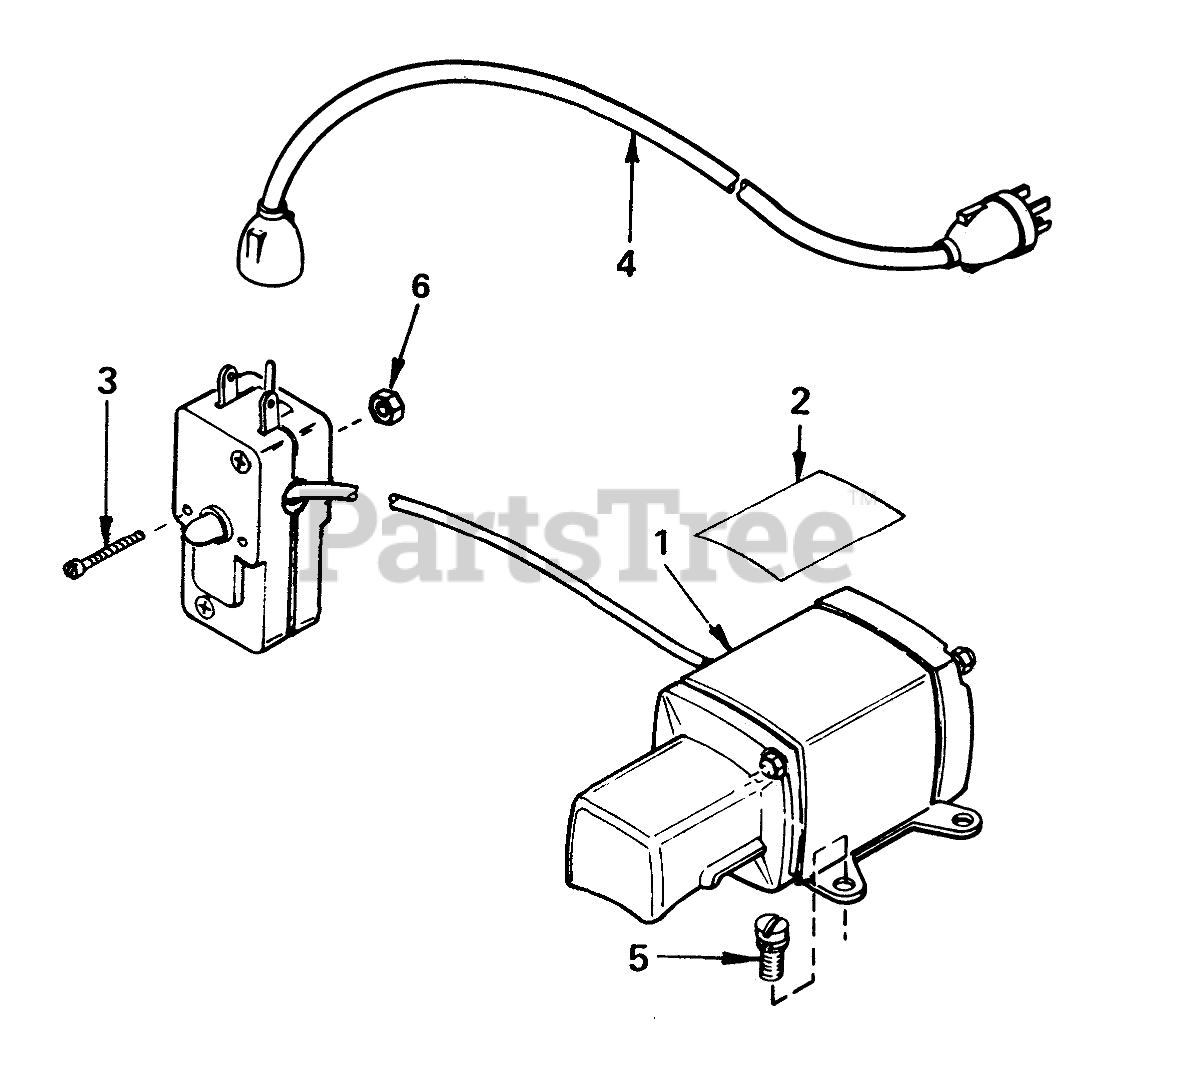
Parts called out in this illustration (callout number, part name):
1	Motor, Cranking (CSA Approved) (Incl. #2 thru 6)
2	Decal
3	Screw, Pan Hd.
4	Cord-Extension
5	Screw (T-30, 1/4-20 x 23/32)
6	Nut & Lockwasher
